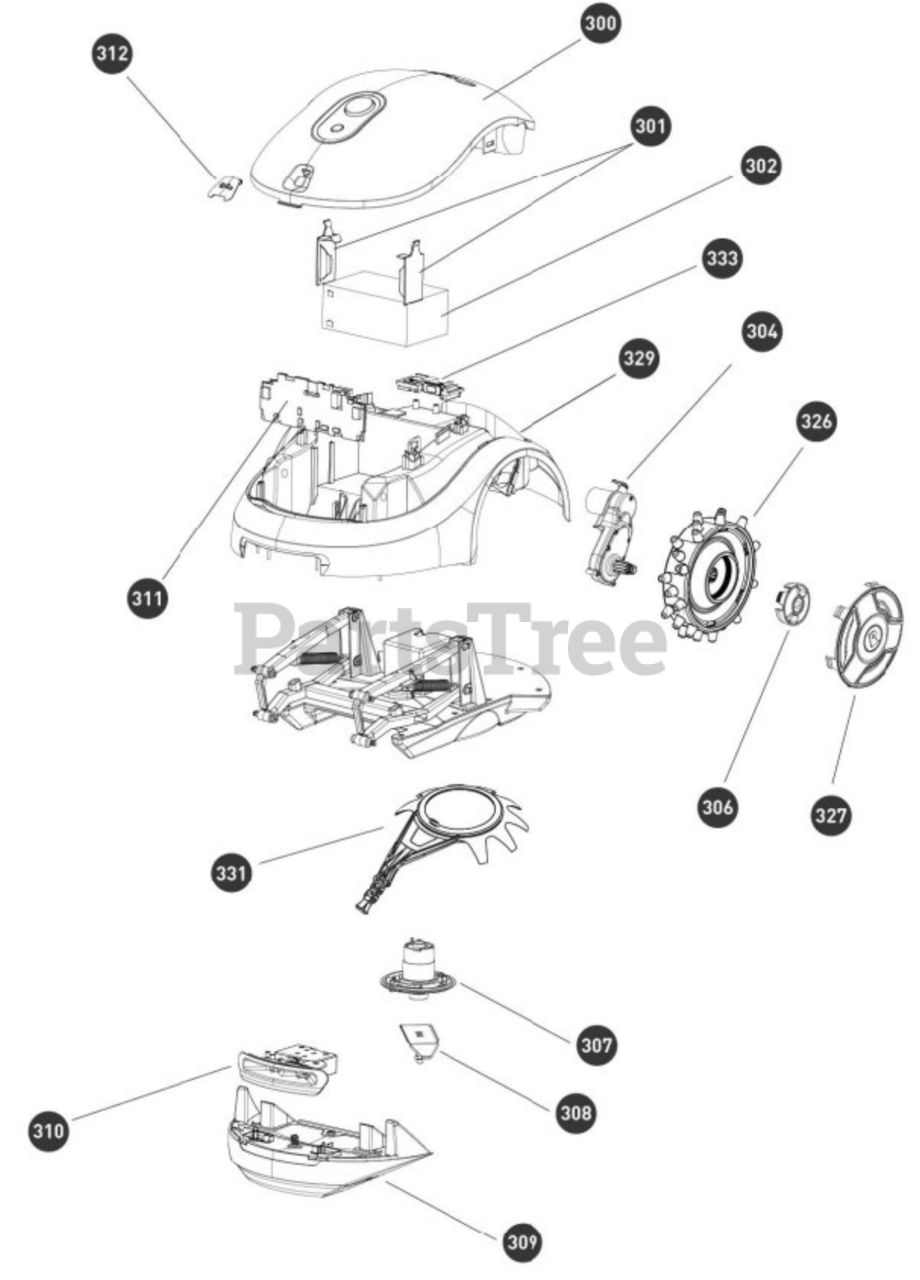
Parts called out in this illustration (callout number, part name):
300	COVER ASSY (GRN)AND DISABLING RX
301	BATTERY LOCKERS RX
302	BATTERY (RX)
304	DRIVE MOTOR RX
306	WHEEL LOCK CAPS RX
307	MOWING MOTOR RX
309	SKI ASSEMBLY RX
310	RX NOZZLE ASSEMBLY
311	MAIN BOARD RX
312	DISABLING DEVICE FOR RX
326	RX DRIVE WHEEL SPIKES OVERMOLD
327	RX ROBOMOW WHEEL PLATE
329	RX CHASSIS
331	MULCH CLEANER ASSEMBLY RX
333	GSM/RCM (ALL MODELS)
